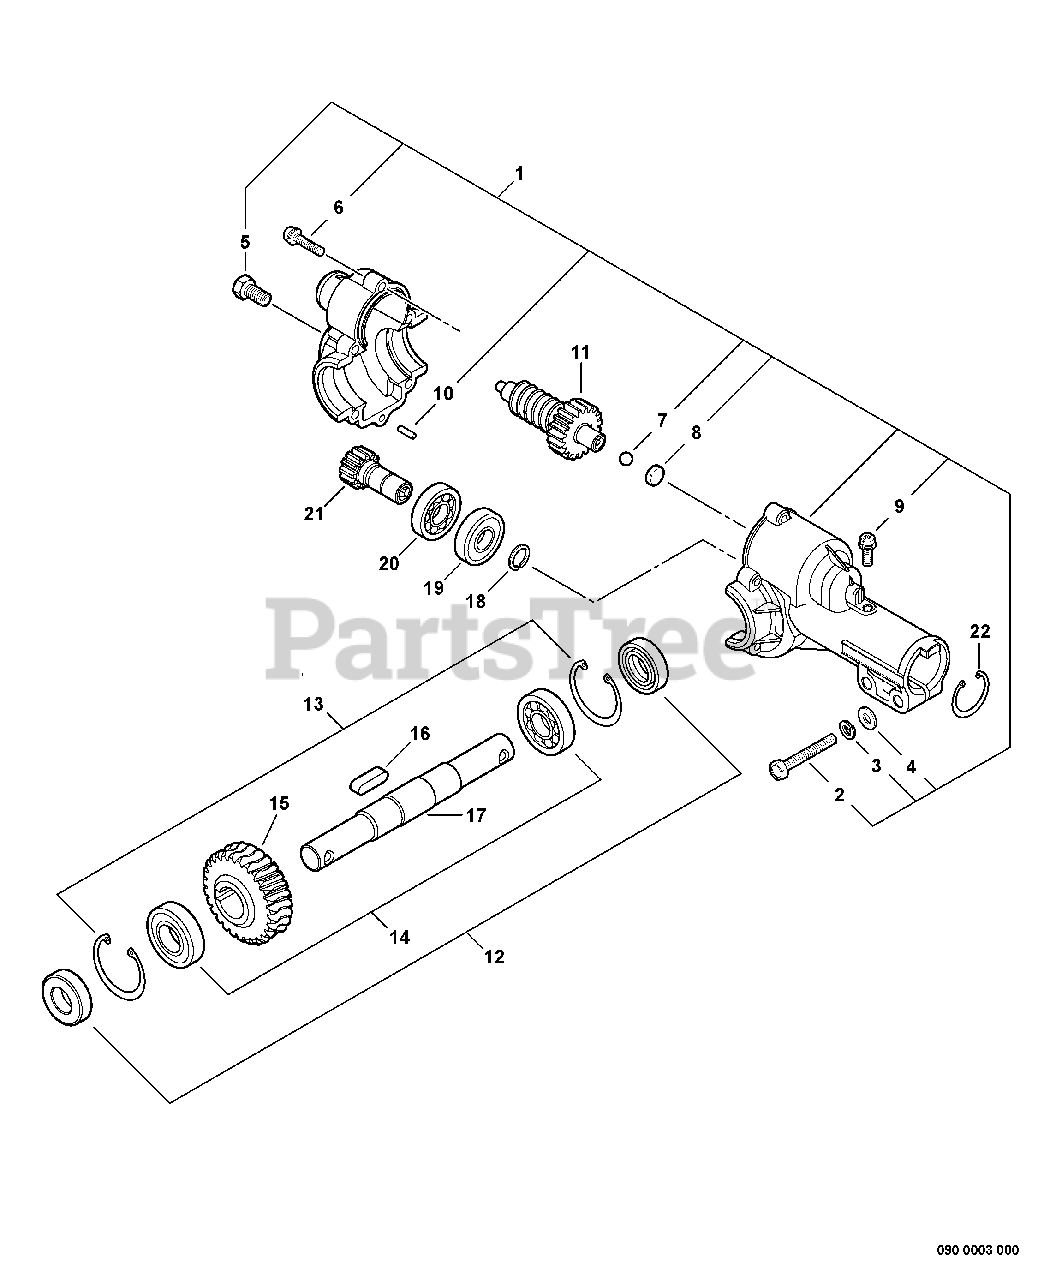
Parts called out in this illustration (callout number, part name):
1	GEAR CASE ASSY
2	BOLT - 6X25
3	LOCKWASHER - 6
4	WASHER - 6
5	BOLT - 8X8
6	SCREW - 4X25
7	BALL, STEEL
8	WASHER - 3
9	SCREW - 5X14
10	PIN - LOCATING
11	GEAR - WORM
12	SEAL, OIL - 17
13	RING, RETAINING - 30
14	BEARING, BALL - 6903
15	WHEEL, WORM
17	SHAFT, WORM GEAR
18	RING, RETAINING - 9
19	BEARING, BALL - 609
20	BEARING, BALL - 609
21	GEAR - DRIVE
22	RING, RETAINING - 25
